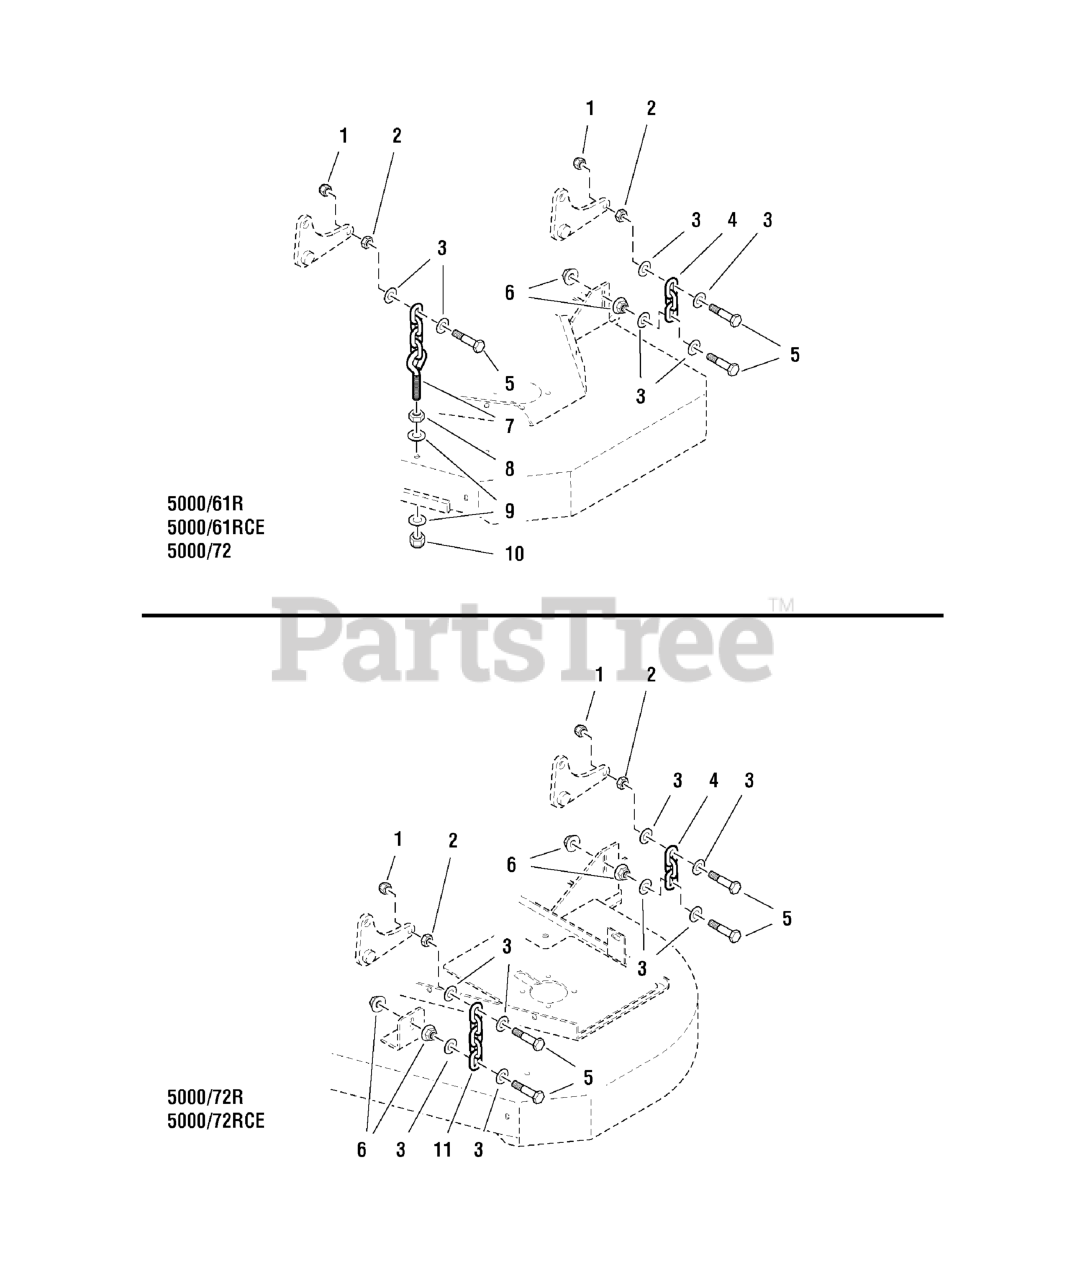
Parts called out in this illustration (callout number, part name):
1	NUT, 3/8-16 HEX NYLON LOCK
2	NUT, 3/8-16 HEX JAM
3	WASHER, 3/8 SAE
4	CHAIN, 3 LINKS
5	BOLT, 3/8-16 X 1-3/4" GD5 CZ
6	NUT, 3/8-16 Hex Serrated Flange
7	HANGER, FRONT DECK - 4 LINK, 5.5" EB
8	NUT, 1/2-13 Hex
9	WASHER, 1/2 SAE
10	NUT, 1/2-13 HEX NYLON LOCK
11	CHAIN, 5 LINKS
